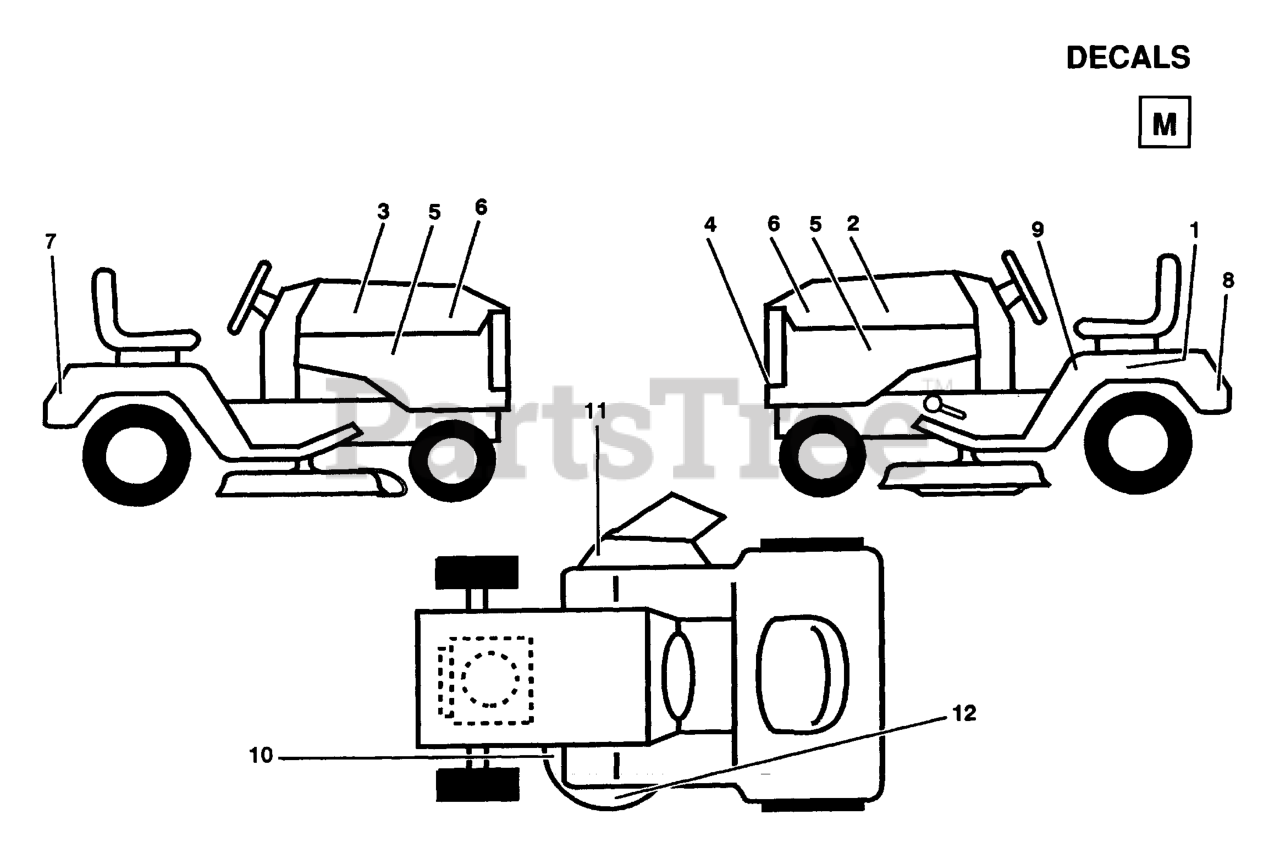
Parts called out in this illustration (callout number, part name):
2	DECAL HOOD STR RH NLA
3	DECAL HOOD STR LH NLA
4	DECAL GRILL HUSQ NLA
5	DECAL SIDE PANEL
6	DECAL HOOD LT100
7	DECAL FENDER NLA
8	DECAL CERTIFICATION
